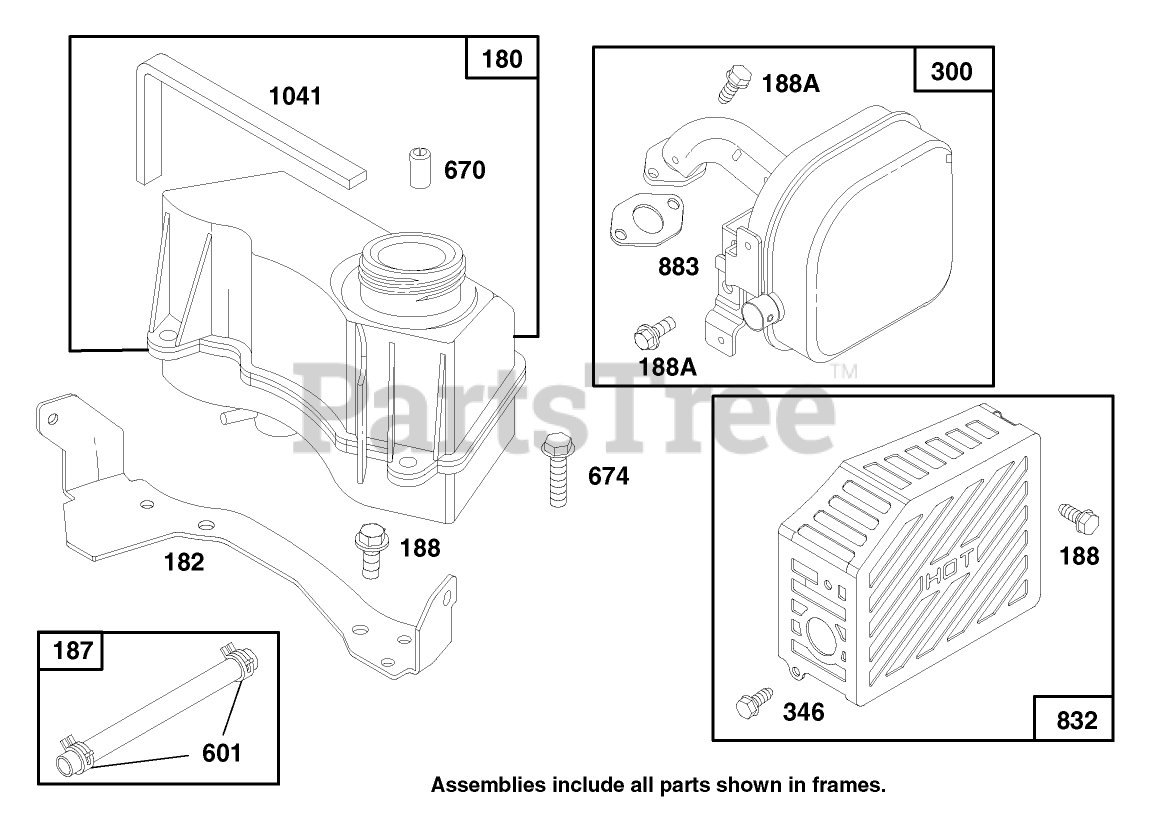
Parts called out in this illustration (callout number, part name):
180	TANK ASSY - FUEL
187	BRIGGS 296004
188	SCREW - HEX HEAD
300	MUFFLER - EXHAUST
670	SPACER
674	SCREW - HEX HEAD
